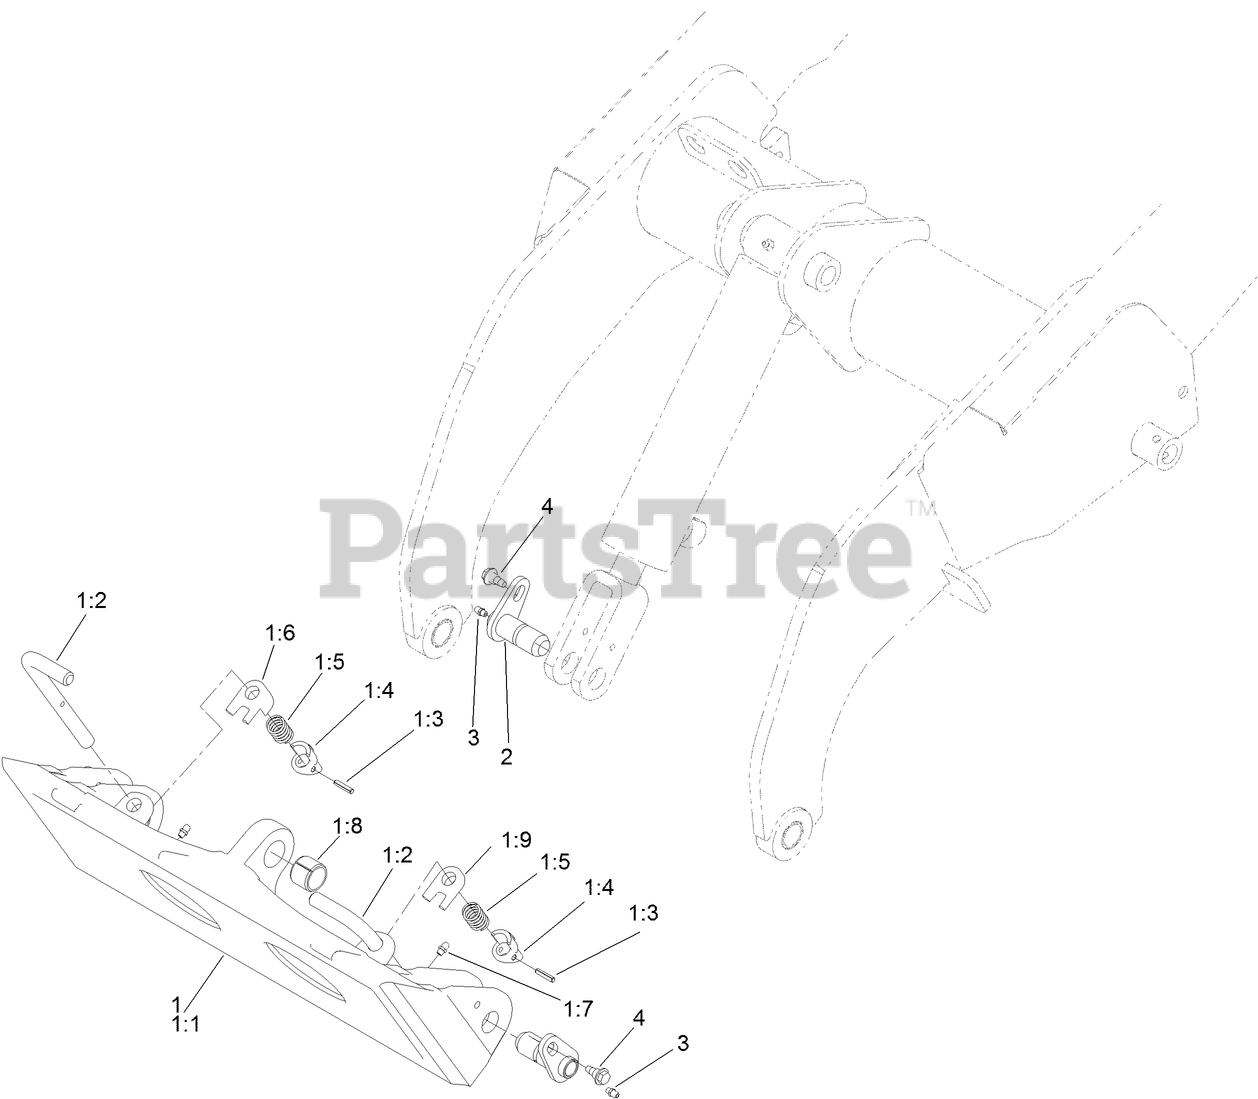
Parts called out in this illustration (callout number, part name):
1	QUICK ATTACH ASM
1:1	MOUNT-QTACH
1:3	SPRING-COMPRESSION
1:4	STOP-RH
1:5	STOP-LH
1:6	PIN-LOCKING
1:7	PIN-GROOVED
1:8	FITTING-GREASE
1:9	BUSHING-TENSION
2	PIN-PIVOT
3	FITTING-GREASE
4	BOLT-SHOULDER
